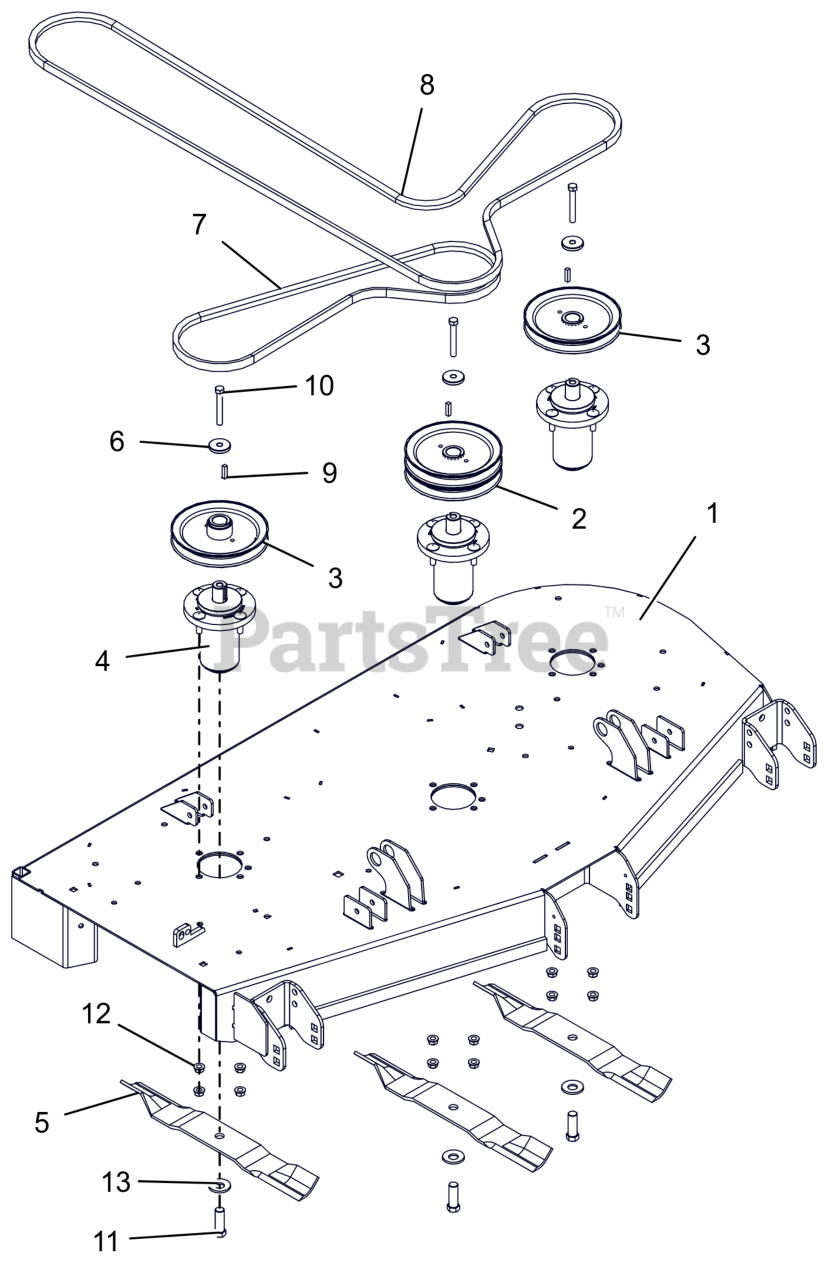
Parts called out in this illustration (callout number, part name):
1	KIT,DECK-52" W/DECALS-GRAVELY
2	PULLEY, DOUBLE-1"ID X 6.75"OD
3	PULLEY, V-1" ID X 6.75" OD
4	ASM, MAINT FREE ALUM SPINDLE
5	BLADE, 18"
6	RETAINER, SHEAVE
7	V-BELT, B-COGGED
8	V-BELT, HB SECTION
9	KEY, SQ .25X.25X1.00 RC 40-50
10	BLT, HEX .38-16X2.75 G8 ZCC
11	BLT, HEX .62-18X1.75 G8 ZCC
12	NUT-LK-CTR-FLG .375-16 GF ZCC
13	WSHR-BLVL .669X1.535X.138
